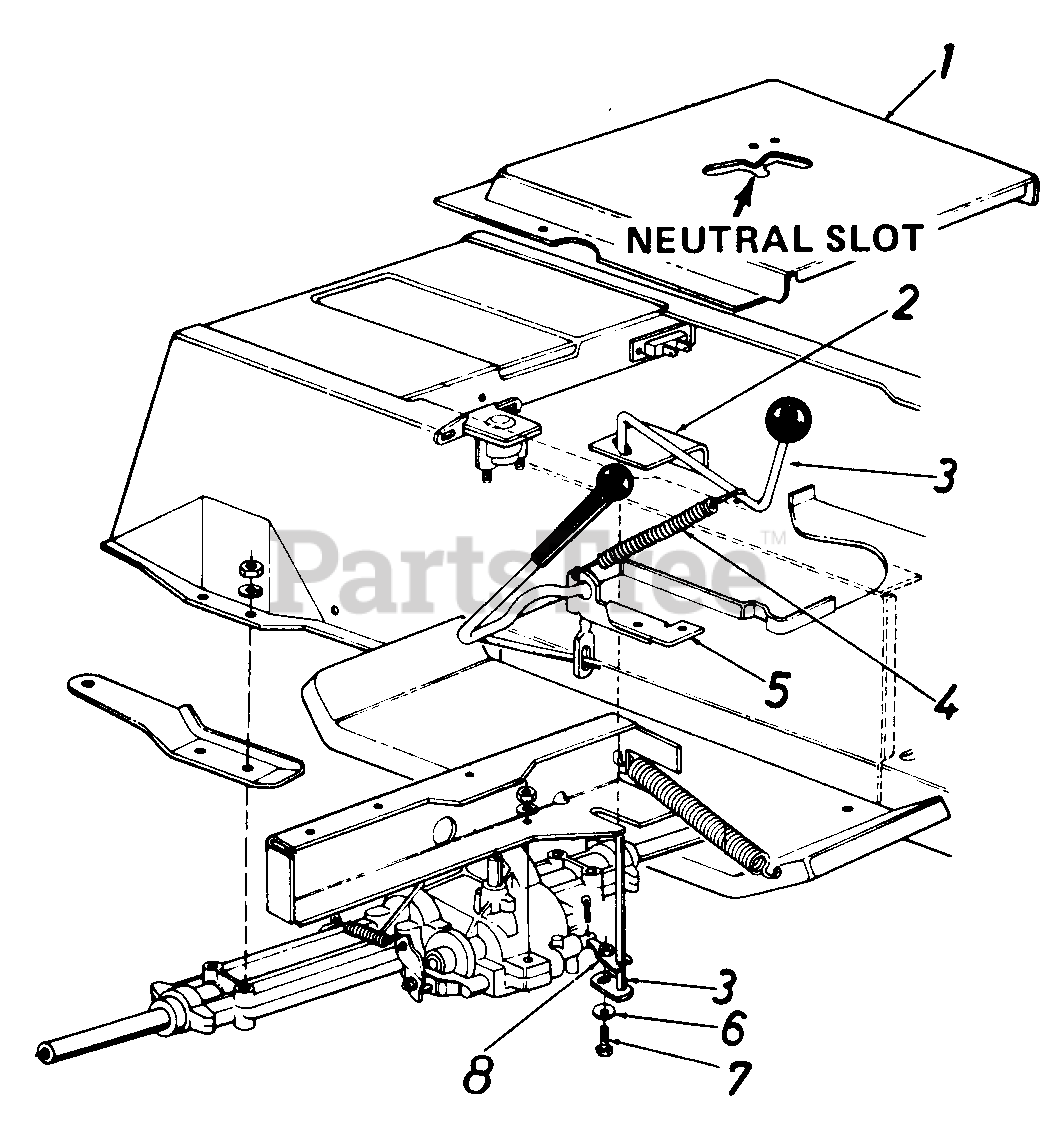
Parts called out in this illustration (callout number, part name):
1	Shift Cover
2	Shift Lever Bracket
3	Shift Lever Ass'y.
4	Extension Spring
5	Brake Lever Bracket
6	Belle-Wash. .25" I.D. x .75" O.D.
7	Hex Bolt 1/4-28 x .75" Lg.
8	Shift Lever Link Ass'y.
